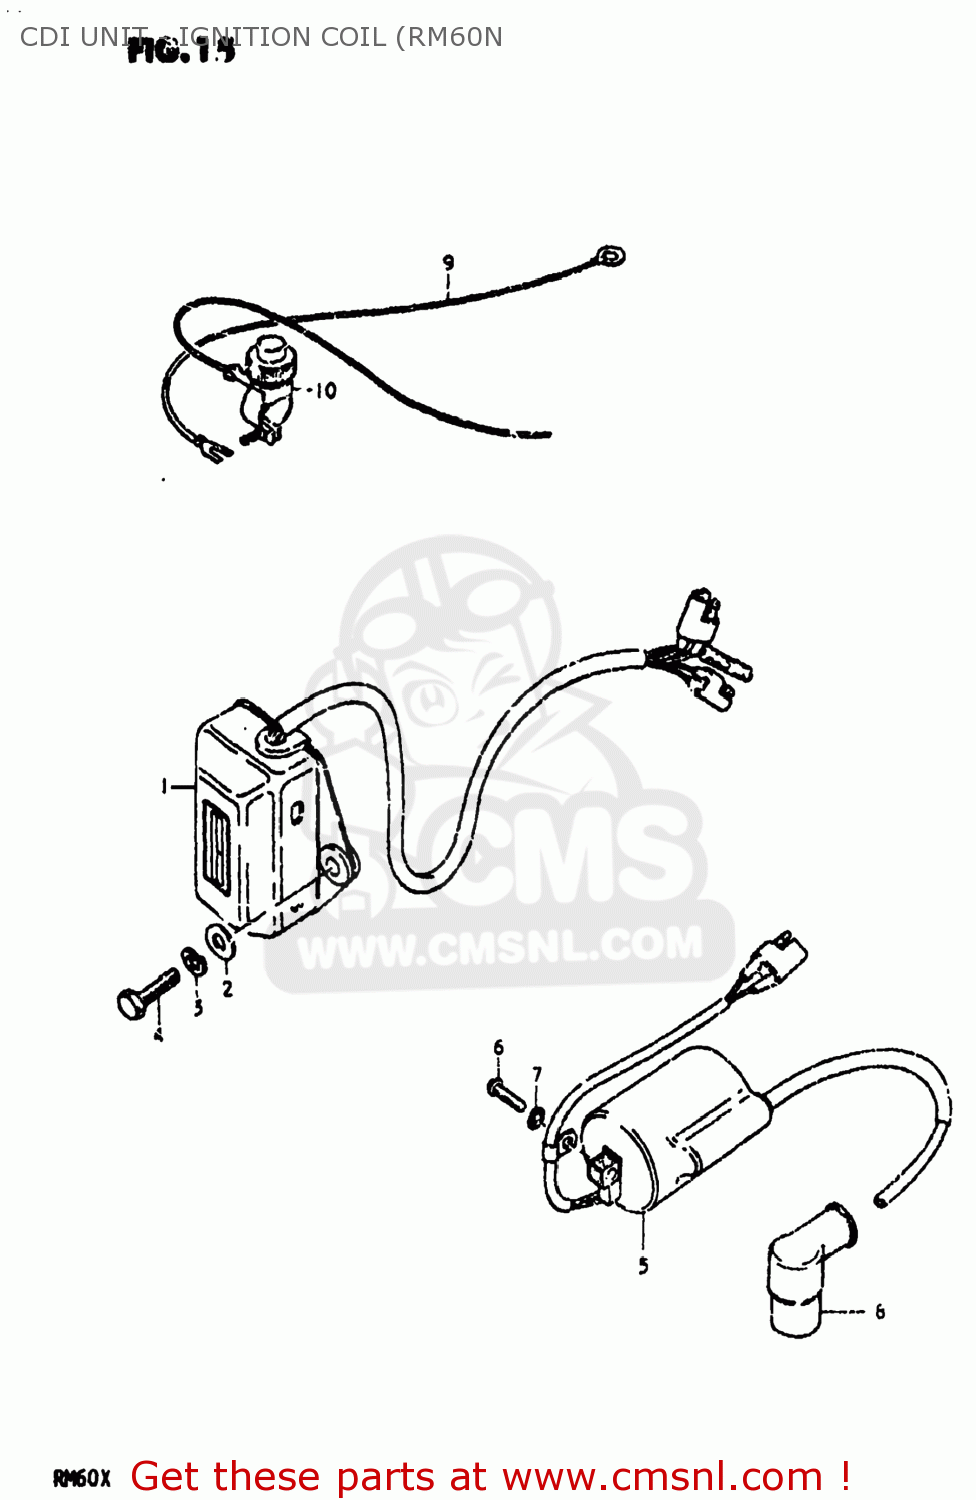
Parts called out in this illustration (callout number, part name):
1	CDI UNIT ASSEMBLY
2	WASHER
3	LOCK WASHER
4	BOLT
5	COIL ASSY,IGNITION
6	SCREW 5X20
7	LOCK WASHER
8	CAP,SPARK PLUG
9	WIRE,ENGINE STOP EARTH
10	SWITCH ASSEMBLY
